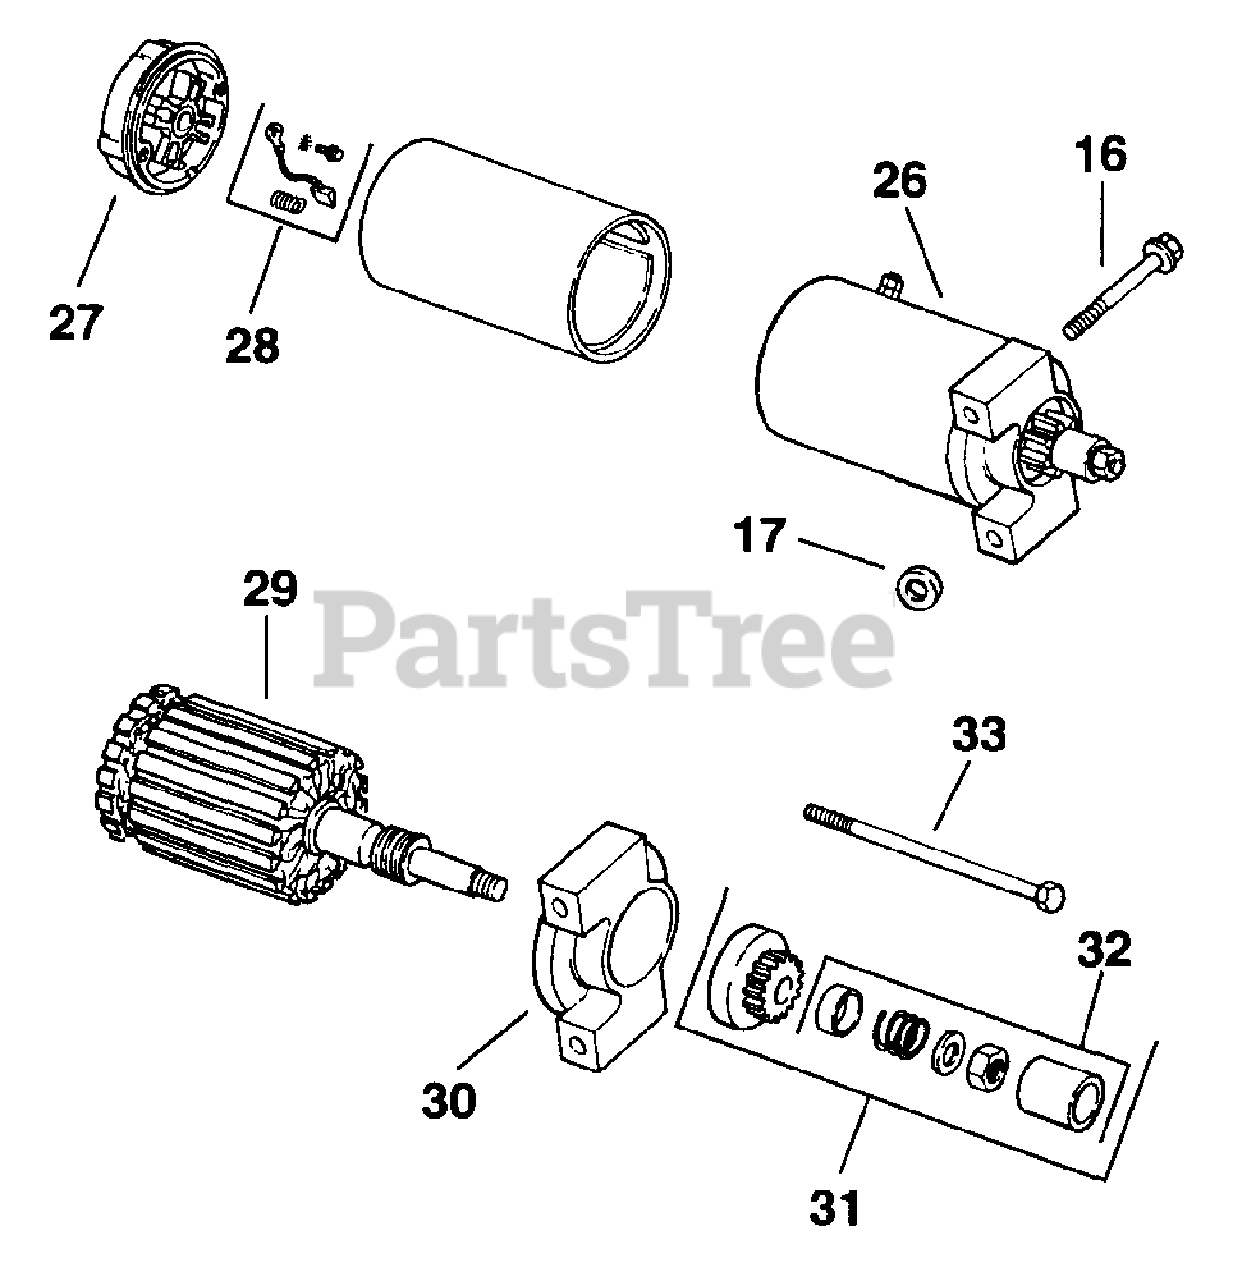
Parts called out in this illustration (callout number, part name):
17	WASHER, FLAT 11/32"
26	STARTER - USE 12 098 12
27	CAP - USE 12 227 10
28	KIT - USE 82 755 28
29	ARMATURE - DISCONTINUED
30	CAP - USE 12 227 05
31	DRIVE KIT - USE 12 755 53
32	DRIVE KIT - USE 12 755 53
33	SCREW - DISCONTINUED
5235701-S	Lubricant, Inertia Drive Starter (0.25 oz.)
